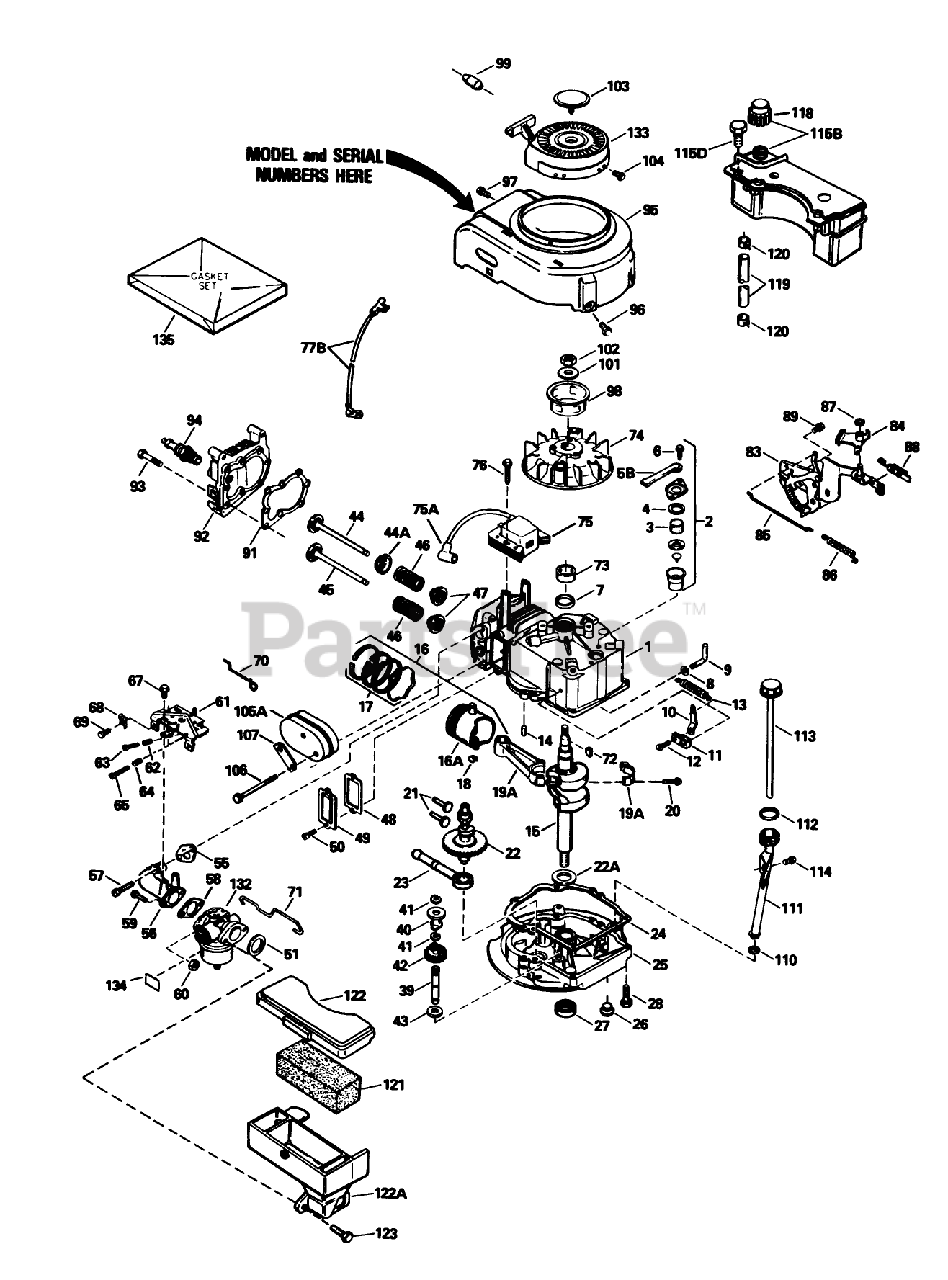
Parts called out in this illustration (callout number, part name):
1	Cylinder Assembly (Incl. Ref. #7 14)
2	Breather Assy. (Incl. Ref. #46 thru 51)
3	Element-Breather
4	Gasket-Breather
5B	Tube, Breaker
6	Screw (10-24 x 9/16)
7	Seal-Oil
8	Washer-Flat
9	Rod, Governor (Incl. No. 36)
10	Governor Lever
11	Clamp-Lever, Governor
12	Screw
13	Spring Governor
14	Pin-Dowel
15	Crankshaft Assy.
16	Piston-Pin Ring Assy. (Std.)(Incl. Ref. #16A, 17 18)
16	Piston-Pin Ring Assembly (.010 oversize)(Incl. Ref. #16A, 17 18)
16	Piston, Pin Ring Assy. (.020 Oversize)(Incl. Ref. #13A, 14, 15)
16A	Piston Pin Assy. (Std.)(Incl. Ref. #14)
16A	Piston Pin Assembly (.010 oversize)(Incl. Ref. #18)
16A	Piston Pin Assy. (.020 Oversize) (Incl. Ref. #14)
17	Ring Set-Piston (Std.)
17	Ring Set, Piston(.0100versize)
17	Ring Set (.020" OS)
18	Ring-Retaining, Piston Pin
19A	Rod Assembly, Connecting (Incl. Nos. 17 18)
20	Bolt-Rod, Connecting
21	Lifter-Valve
22	Camshaft(Mech.Comp. Release)
22A	Washer-Thrust
23	Oil Pump ASM
24	Gasket
25	Flange-Mounting (Incl. Ref. #26, 27 39)
26	Plug Oil Drain
27	Seal-Oil
28	Screw (1/4-20 x 1-1/4)
39	Shaft-Governor
40	Spool-Governor
41	Ring-Retaining
42	Governor Gear ASM
43	Washer
44	Valve, Intake (Std.) (Incl. Ref. #40)
44	Valve, Intake (1/32" oversize)(Incl. No. 40)
44A	Seal Assy., Intake
45	Valve, Exhaust (Std.)(Incl. No. 40)
45	Valve, Intake (1/32" oversize)(Incl. No. 40)
46	Spring-Valve
47	Cap-Valve, Spring
48	Gasket-Cover, Valve
49	Cover-Valve
50	Screw
51	Gasket-Cleaner, Air
55	Gasket-Intake Pipe
56	Pipe-Intake (Incl. Ref. #59)
57	Screw (1/4-20 x 1)
58	Gasket
60	Nut and Lock Washer (1/4-28)
61	51089 SUPP TO MANUA
62	61709/GIL1515A/95-5
63	Screw
64	Spring-Compression
65	Screw
67	Screw (10-24 x 9/16)
68	Conduit
69	Screw (10-32 x 3/8)
70	2035A67 ADD.ASSEMBL
71	Link-Throttle
72	Key-Flywheel
73	Spacer
74	Flywheel
75	Solid State
75A	Cover-Spark Plug
76	Screw
77B	Ground Wire
83	Bracket-S.E. Brake
84	Lever-Brake
85	Link-Control
86	Spring-Extension
87	Ring-Retaining
88	Terminal
89	Screw (1/4-20 x 3/8)
91	Gasket-Cylinder Head
92	Head-Cylinder
93	Screw (5/16-18x1-1/2)
94	Spark Plug-Resistor (R J19 L M)
95	Housing-Blower
96	Screw (1/4-20 x 1/2)
97	Screw (10-24 x 9/16)
98	Hub-Starter
99	Retainer-Starter Rope
101	Washer-Belleville
102	Nut-Flywheel
103	Plug Starter
104	Screw, Hex Hd.
105A	Muffler
106	Screw
107	Plate-Lock
110	Gasket
111	Oil Fill Tube
112	O-Ring
113	Dipstick
114	Screw (10-32 x 1/2)
115B	Tank Assembly-Fuel (Incl. Ref. #102)
115D	Screw (10-32 x 35/64)
118	Cap-Fuel
119	Line-Fuel
120	Clamp-Line, Fuel
121	Filter-Air Cleaner
122	Cover-Air Cleaner
122A	Body, Air Cleaner
123	Screw
132	Carburetor (Incl. Ref. #58)
133	Starter-Rewind
134	Decal-Primer
135	Gasket Set (Incl. Items Marked *)
